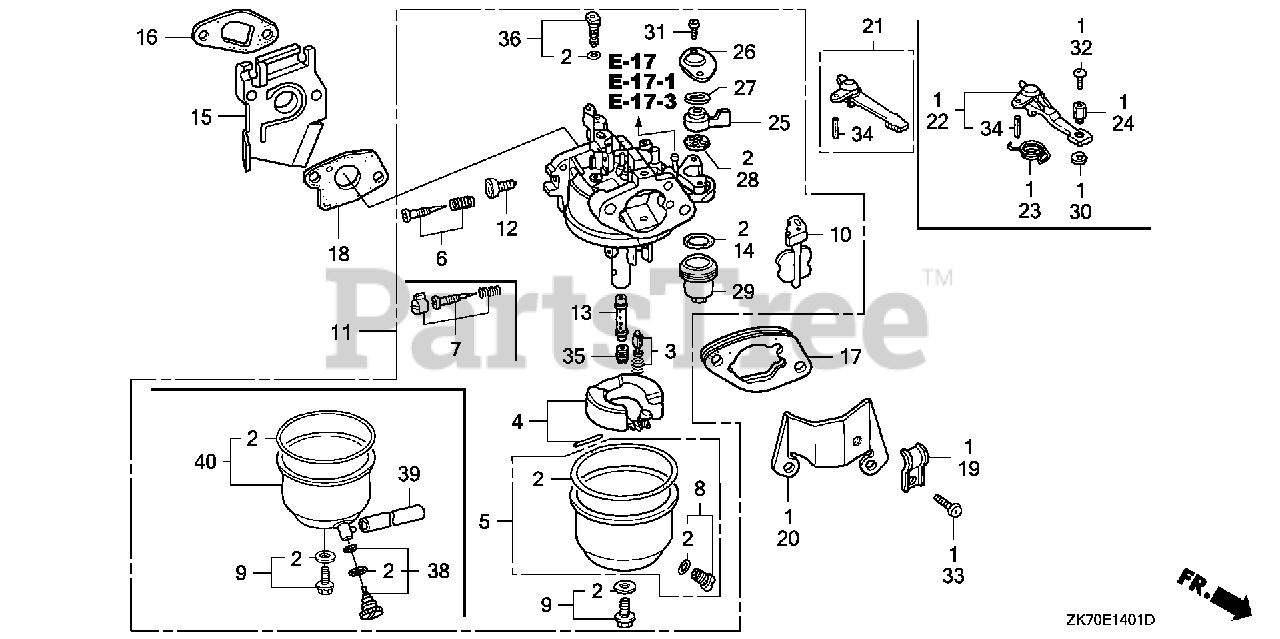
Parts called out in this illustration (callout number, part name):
2	GASKET SET
3	VALVE SET, FLOAT (CARBURETOR NO.) (SEAT NOT INCLUDED)
4	FLOAT SET
5	CHAMBER SET, FLOAT (CARBURETOR NO.)
7	SCREW SET (Honda Code 4219879). (CARBURETOR NO.)
8	SCREW SET, DRAIN (Honda Code 1672187). (CARBURETOR NO.)
9	SCREW SET B
9	SCREW SET
10	CHOKE SET
11	CARBURETOR ASSY. (BE60B B)
12	SCREW, THROTTLE STOP
13	NOZZLE, MAIN
14	GASKET, FUEL STRAINER CUP
15	INSULATOR, CARBURETOR
16	GASKET, INSULATOR
17	SPACER, CARBURETOR
18	GASKET, CARBURETOR
21	LEVER, CHOKE (STD)
25	LEVER, VALVE
26	PLATE, LEVER SETTING (CARBURETOR NO.)
27	SPRING, PETCOCK LEVER (CARBURETOR NO.)
28	GASKET, VALVE
29	CUP, FUEL STRAINER
31	SCREW, PAN (3X6)
34	PIN, SPRING (2X12)
35	JET, MAIN (#55) (CARBURETOR NO.) Use up to Engine SN BE03A J.
35	JET, MAIN (#58) Use from Engine SN BE30B E.
35	JET, MAIN (#60)
36	JET SET, PILOT (#35)
